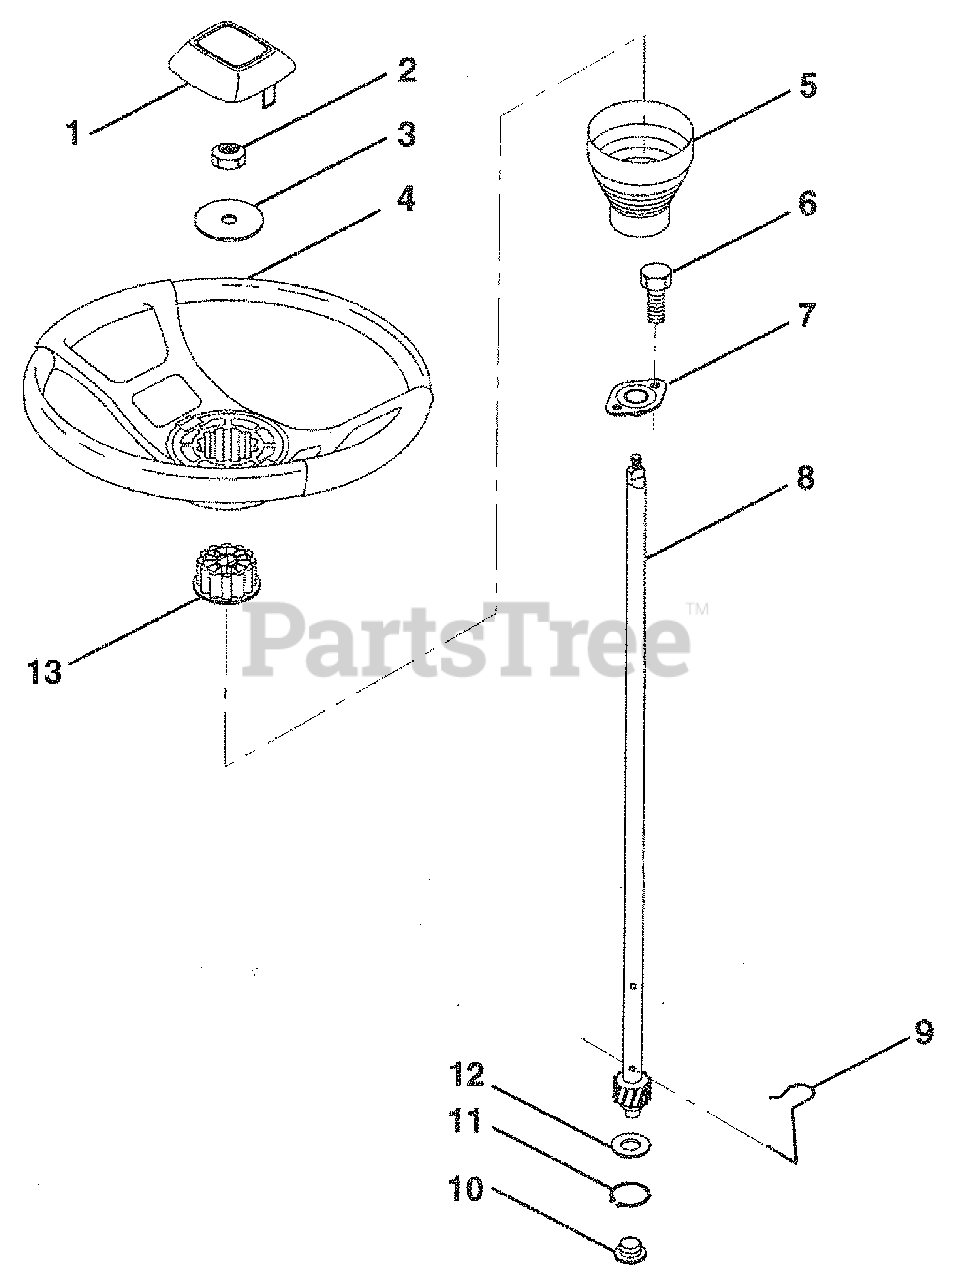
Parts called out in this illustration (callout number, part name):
1	Insert, Wheel, Steering
2	Nut, Lock 3/8-24 UNF
3	Washer 12/32 x 2-3/8 x 8 Ga.
4	Wheel, Steering
5	Sleeve, Steering
6	Screw, Hex #10-16x1/2 TY-B
7	Bushing, Steering
8	Shaft Steering
9	Clip, Steering
10	Bushing, Lower, Steering
11	Ring, Retaining
12	Washer 21/32 x 1 x16Ga.
13	Adaptor, Wheel, Steering
